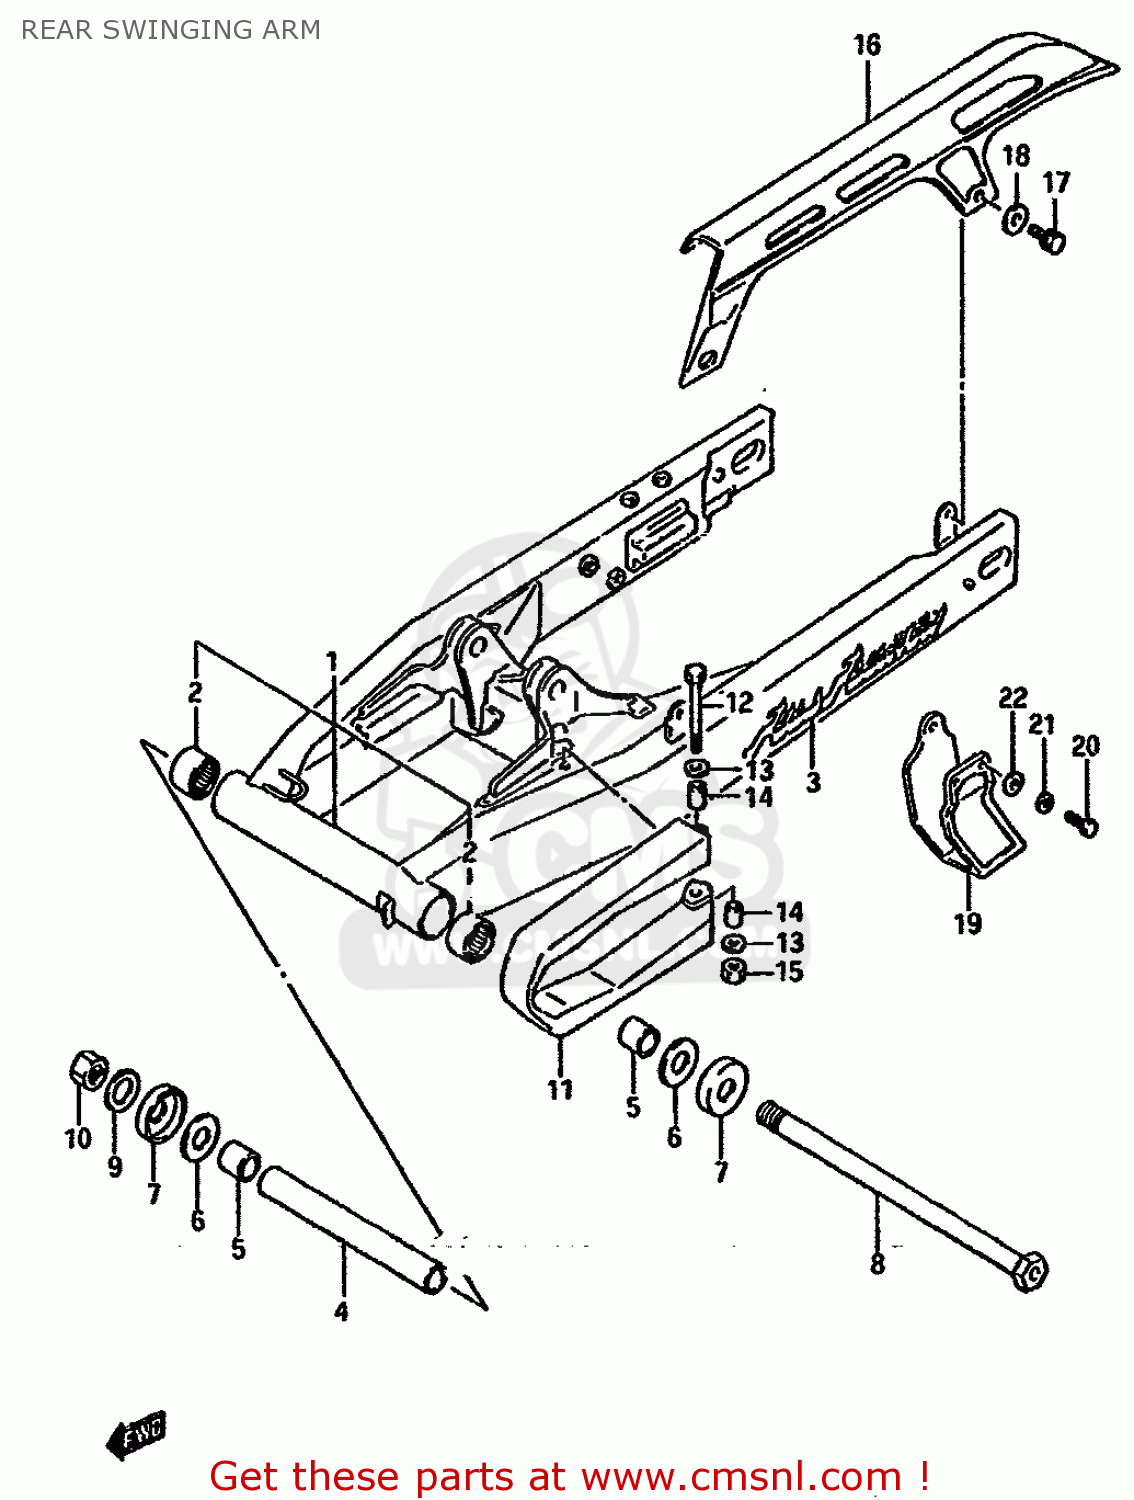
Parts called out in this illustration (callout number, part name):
1	SWINGING ARM ASSY,REAR (BLUE)
2	BEARING(22X29X20)
3	EMBLEM
4	SPACER,RR SWGARM PIVOT CTR
5	SPACER,RR SWGARM PIVOT
6	WASHER
7	SEAL,RR SWGARM PIVOT DUST
8	SHAFT
9	WASHER (BLACK)
10	NUT (BLACK)
11	BUFFER,CHAIN TOUCH DEFENSE
12	BOLT,TOUCH DEFENSE FTG
13	WASHER (5.5X14X1.2)
14	SPACER (6.6X9X6.5)
15	NUT
16	CASE,CHAIN
17	BOLT
18	WASHER
19	GUIDE,CHAIN
20	BOLT
21	WASHER,LOCK
22	WASHER(6.5X16X1.2)
